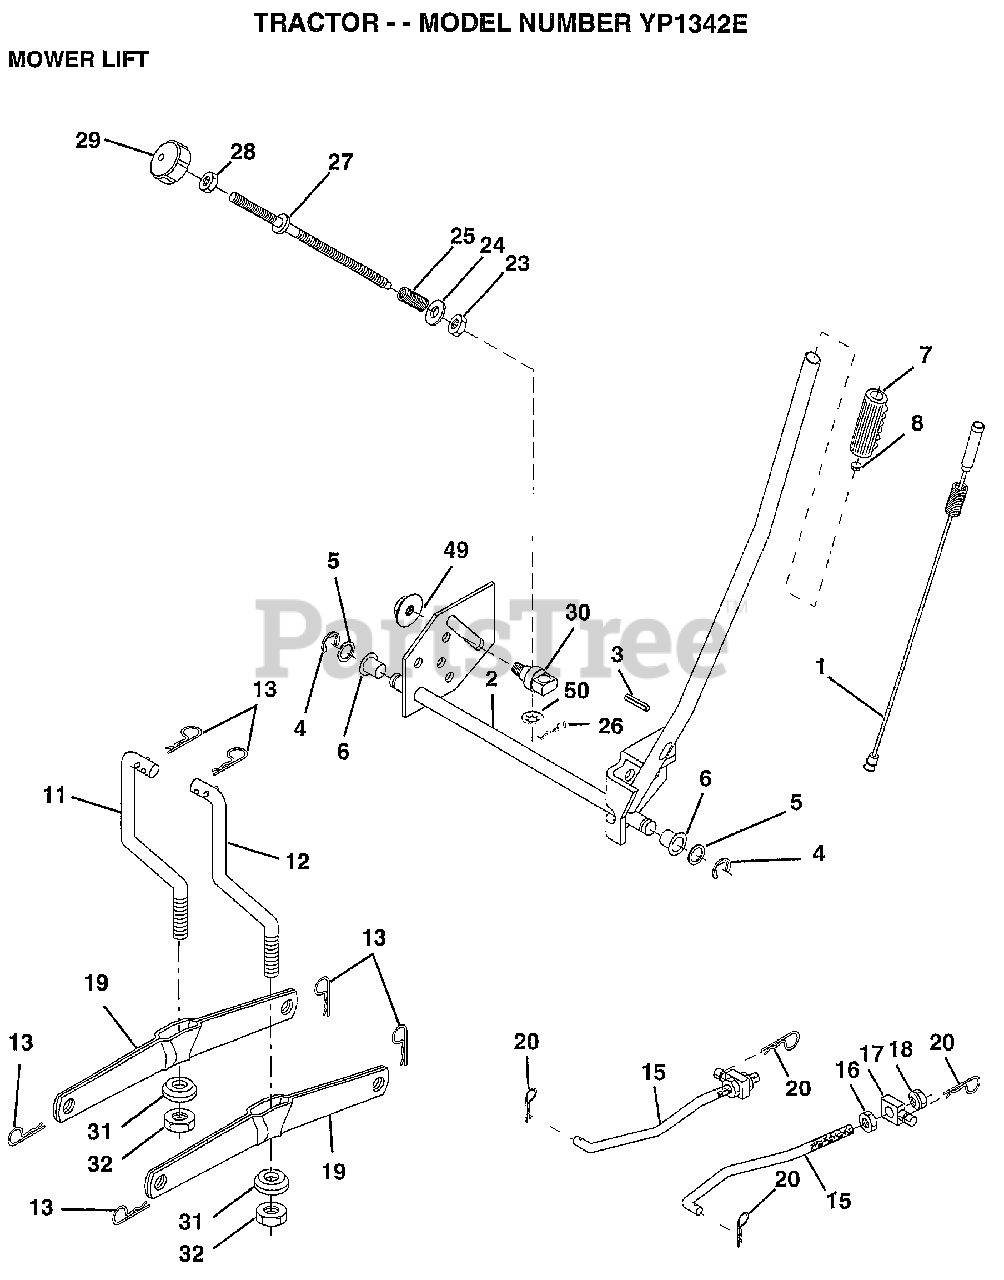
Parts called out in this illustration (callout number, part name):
1	WIRE ASM W.SPRING
2	"SHAFT ASM LIFT,RH"
3	PIN-GROOVE LT
5	WASHER
6	NYLON BEARING
7	GRIP HANDLE
15	LINK.FRONT
16	NUT
17	TRUNION
18	NUT LTV
19	ARM SUSP REAR
20	RETAINER SPRING
23	NUT T
24	WASHER
25	SPRING T
28	NUT
29	KNOB INF 3/8-16
30	TRUNNION
31	BEARING PVT LH
32	NUT.CROWNLOCK.3/8
49	NUT.HXFLG.LOCK.
50	NUT PUSH M
